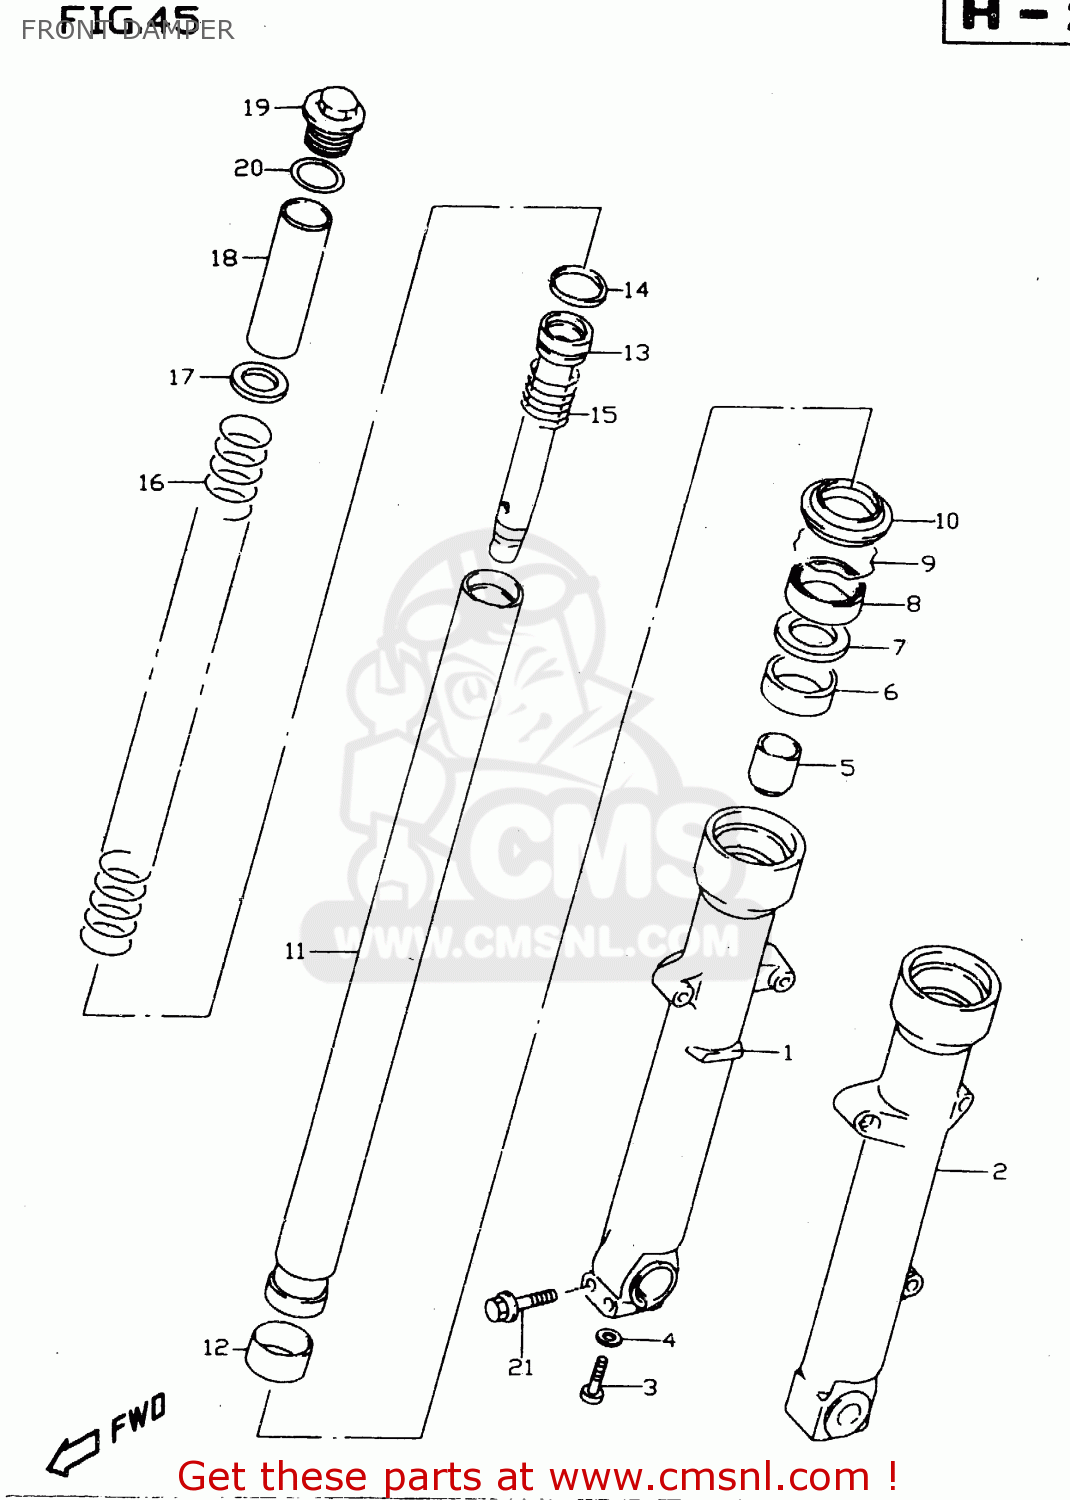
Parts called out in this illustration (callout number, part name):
1	TUBE,OUTER,R
2	TUBE,OUTER,L
3	BOLT(8X27)
4	GASKET (NAS)
5	PIECE,OIL LOCK
6	BUSH,GUIDE
7	SPACER,SEAL
8	SEAL,OIL
9	CIRCLIP,FORK OIL SEAL
10	SEAL,DUST
11	TUBE,INNER
12	BUSH,SLIDE
13	PIPE,SEAT
14	RING,PISTON
15	SPRING,REBOUND
16	SPRING,FR
17	SEAT,SPRING LWR
18	SPACER,SPRING
19	BOLT,FORK
20	O RING
21	BOLT
